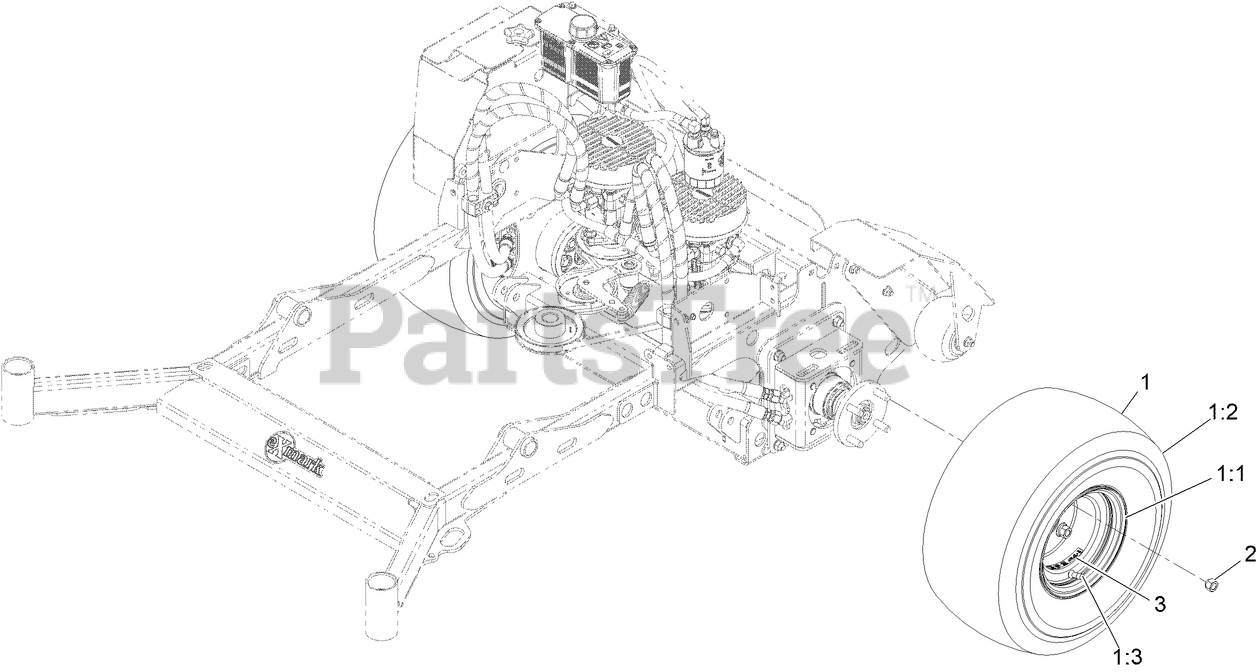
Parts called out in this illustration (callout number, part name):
1	ASM-Whl/Tire K505
1:1	TIRE-K505
1:3	Stem-Valve
2	NUT-LUG
3	DECAL-TORQUE, WHEEL HUB LUG
